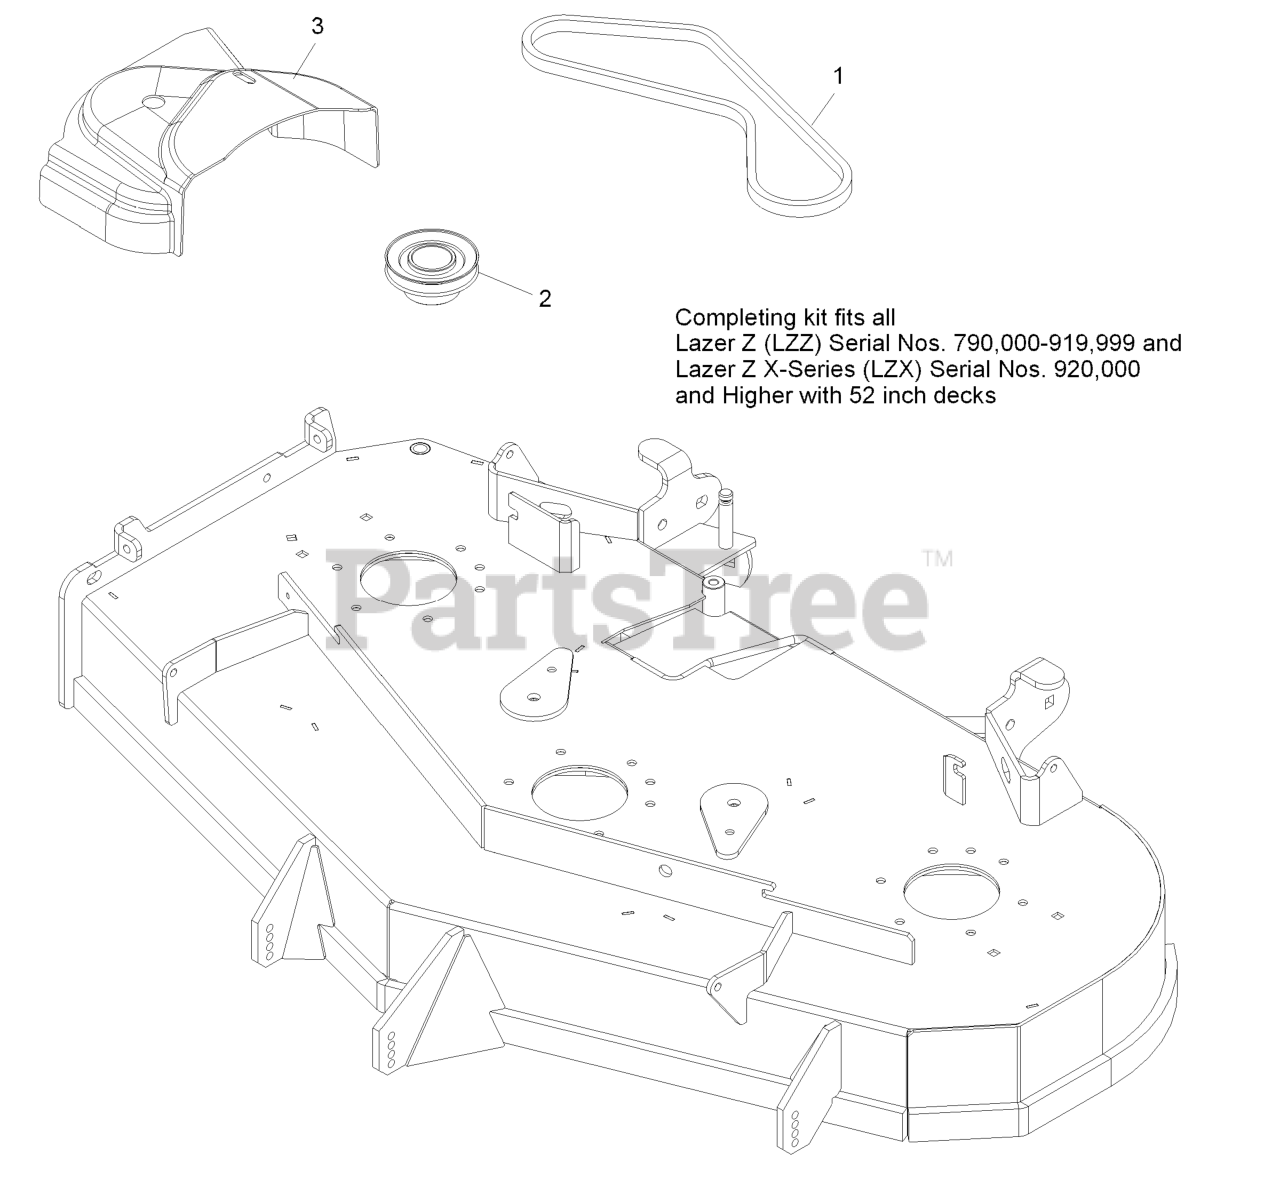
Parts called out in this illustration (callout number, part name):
1	Belt, Blower Drive 52
2	Sheave,Drive Lzuv 526
3	Cover,Belt Uv 52
